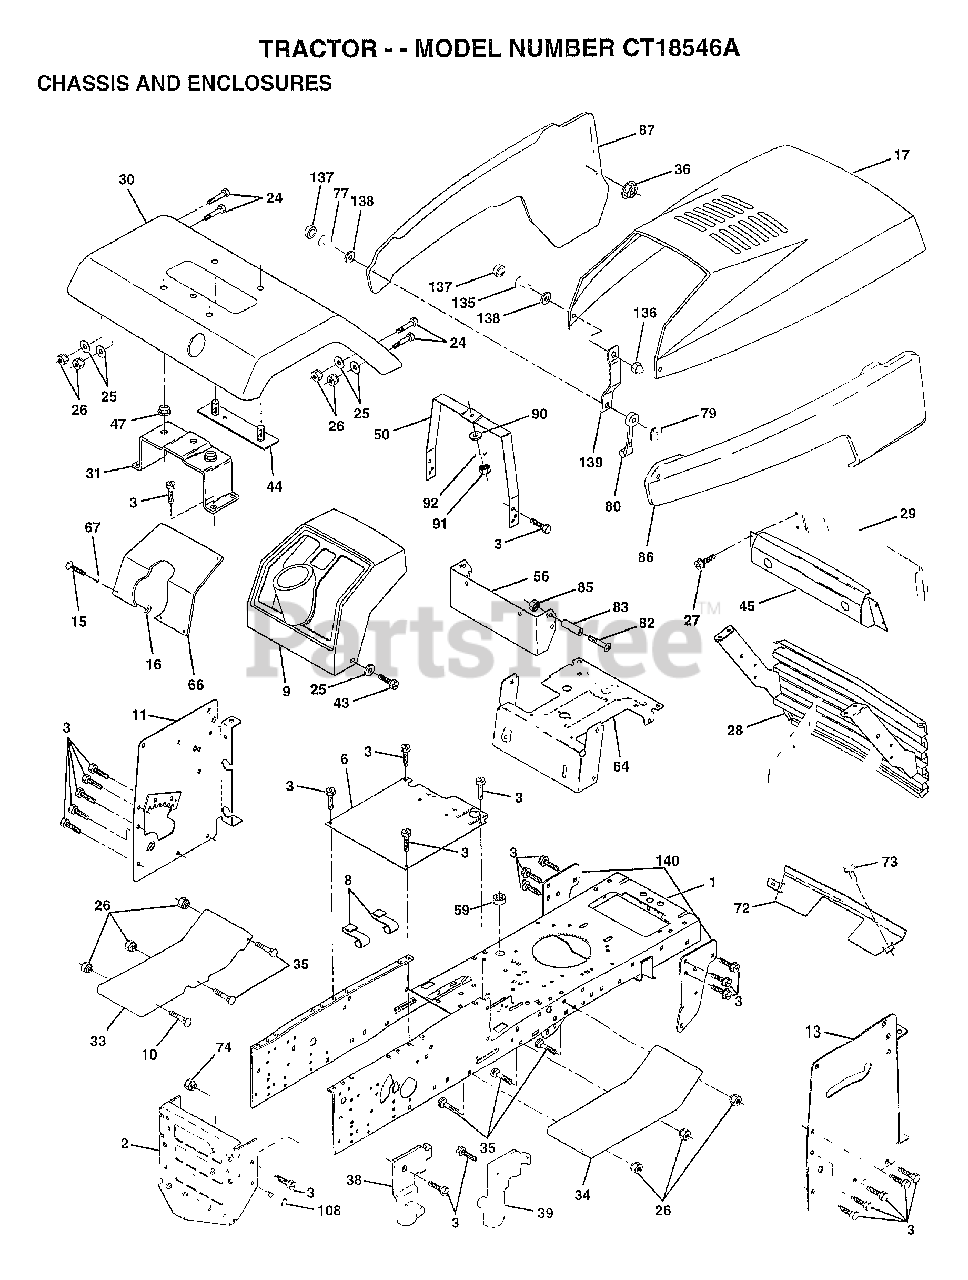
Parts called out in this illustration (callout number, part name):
1	CHASSIS ASM
3	SCREW
6	SADDLE
8	"CLIP,INSULATOR"
9	DASHBOARD BLACK
11	PANEL.DASH.LH.PNT
13	PANEL.DASH.RH.PNT
15	SCREW
17	HOOD PNT YARDPRO
24	BOLT
25	WASHER
26	NUT
28	GRILLE ASM PNT
29	LENS.BAR.CLEAR
30	FENDER PNT
31	BRKT.ASM.FENDER
33	FOOTREST PNT LH
34	FOOTREST.RH.LT/GT
35	BOLT
36	PAL NUT LT
38	BRACKET ASM LH
39	BRACKET ASM RH
43	SCREW
44	STRAP ASM FENDER
45	BEZEL.ASM.
47	NUT-PUSH YT
50	DASH.SUPT.YP/HUSQ
56	EXT DASH LTYT
64	DASH.LOWER.LT
66	"PLATE DASH,SLKSCR"
67	WASHER
72	STRAP.PNT.GRILLE
73	SCREW CRT
77	SCREW
79	WELDNUT
80	HOOD LATCH T
82	SCREW
83	SPACER LT
87	PANEL PNT LH SIDE
90	WASHER PM
92	LOCKWASHER
135	SCREW.10-24X3/8.
136	ACORN NUT RB
137	SNAP CAP LT
138	WASHER LT
139	BKT.SPT.HOOD/PANL
140	BRKT SUSPENSION
